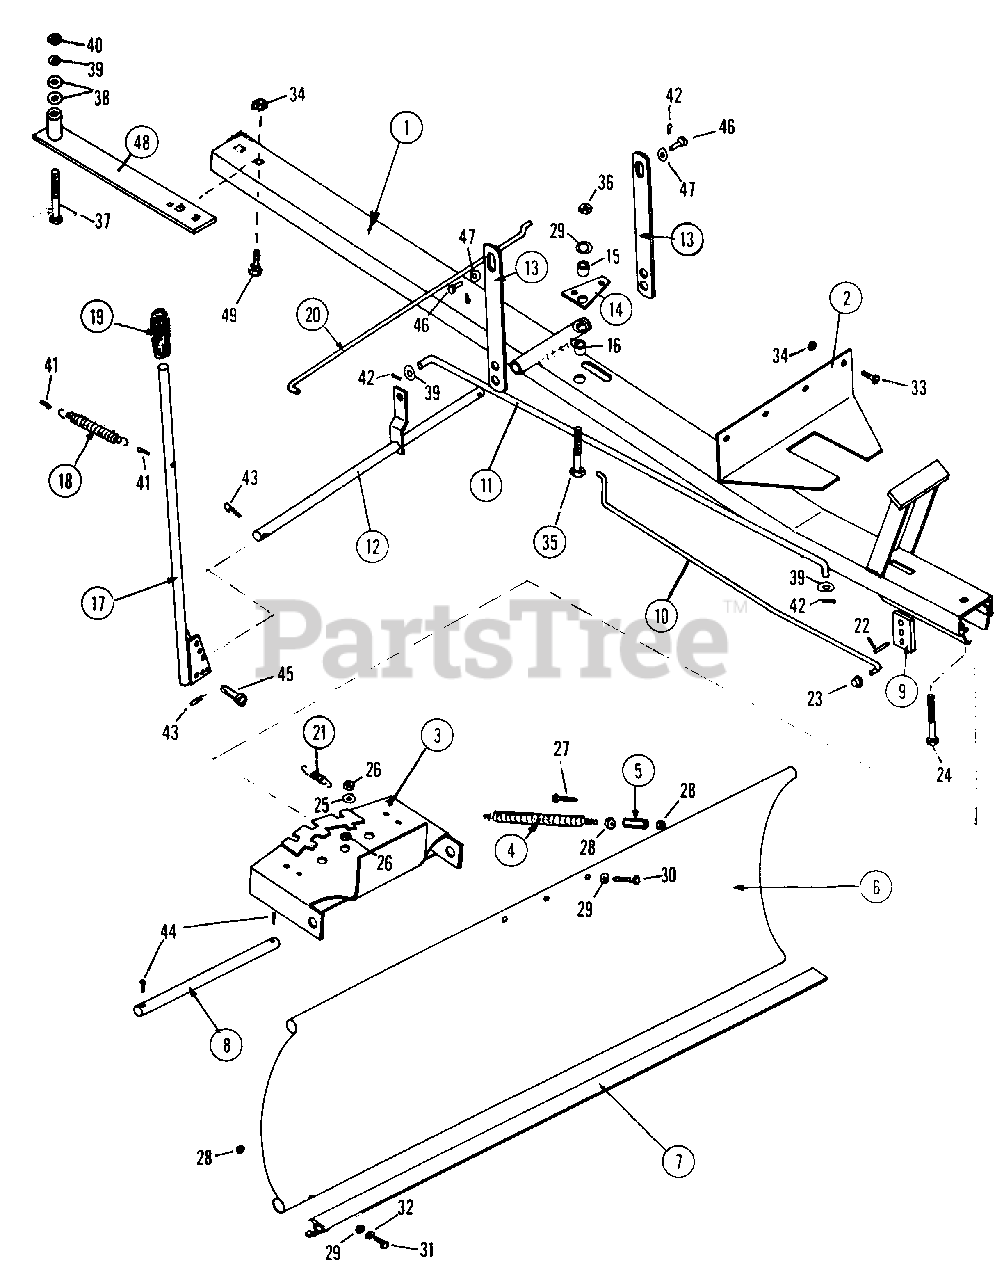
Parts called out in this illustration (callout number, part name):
1	FRAME, PUSH
2	GUIDE, PUSH FRAME
3	PLATE, PIVOT
4	SPRING, BLADE TRIP
5	NUT, COUPLER
6	BLADE, 54" DOZER
7	BAR, 54" BLADE WEAR
8	ROD, BLADE PIVOT
9	BAR, PIVOT LATCH
10	ROD, LATCH SIDE CONTROL
11	ROD, BLADE ANGLING
12	BAR, PIVOT
13	STRAP, BLADE LIFT
14	BELLCRANK, LATCH CONTROL
15	BUSHING, BELLCRANK
16	SPACER, BELLCRANK
17	HANDLE, BLADE ANGLING
18	SPRING, HANDLE RETURN
19	GRIP, HANDLE
20	ROD, LATCH CONTROL (LONG)
21	SPRING, LATCH BAR LOCK
22	PIN, SPIROL 1/4 x 1
23	NUT, 3/4C HALF HEX
24	BOLT, 3/4C x 4 HEX HEAD
25	WASHER, 3/4 ID. x 1-1/8 OD. FLAT
26	NUT, 3/4C HALF HEX
27	BOLT, 3/8C x 1 HEX FULL THREAD
28	NUT, 3/8C HEX
29	WASHER, 3/8" Flat
30	BOLT, 3/8C x 5-1/2 HEX HEAD
31	BOLT, 3/8C x 1 CARRIAGE
32	LOCKWASHER, 3/8
33	BOLT, 1/2C x 1 HEX HEAD
34	LOCKNUT, 1/2C HEX
35	BOLT, 3/8C x 1-1/2 HEX HEAD
36	LOCKNUT, 3/8C HEX
37	BOLT, 5/8C x 4-1/2 HEX HEAD
38	WASHER, 5/8ID x 1-3/8 OD. RUBBER
39	WASHER, 5/8 FLAT
40	LOCKNUT, 5/8C HEX
41	PIN, 3/16 x 1-1/2 COTTER
42	PIN, HAIR COTTER
43	PIN, HAIR COTTER
44	PIN, 5/32 x 1-1/4 COTTER
45	PIN, 3/8 x 1 -1/4
46	PIN, 1/2 x 1 CLEVIS
47	WASHER, 1/2" FLAT
48	EXTENSION, PUSH FRAME (MOUNTING BAR)
49	BOLT, Carriage 1/2-13X1-1/2
